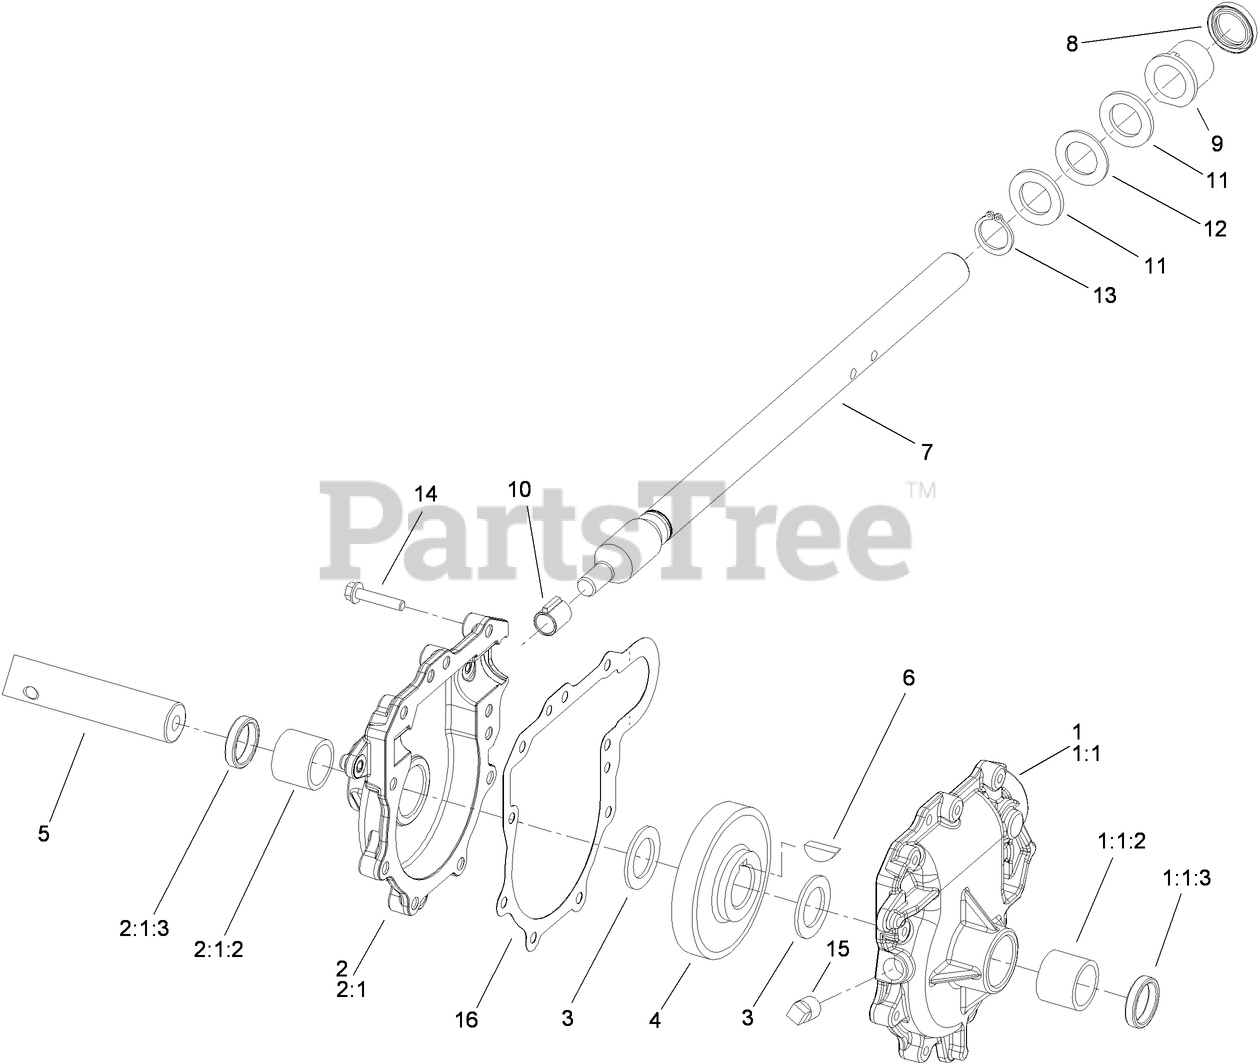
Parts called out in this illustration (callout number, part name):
1	LH AUGER GEARCASE ASM
1:1	Gearcase-Auger, LH
1:1:2	BUSHING-SLEEVE
1:1:3	SEAL-OIL
2	RH AUGER GEARCASE ASM
2:1	Loose Parts Package
2:1:2	BUSHING-SLEEVE
2:1:3	SEAL-OIL
3	WASHER-THRUST
4	GEAR-HELICAL
5	SHAFT-AUGER
6	KEY-WOODRUFF
7	SHAFT-IMPELLER
8	SEAL-OIL
9	BUSHING-INPUT
10	BUSHING-WORM
11	WASHER-THRUST
12	BEARING-THRUST
13	RING-RETAINING, EXT
14	SCREW-HWHTF
15	PLUG-PIPE, SQH
16	GASKET-GEARCASE, AUGER
